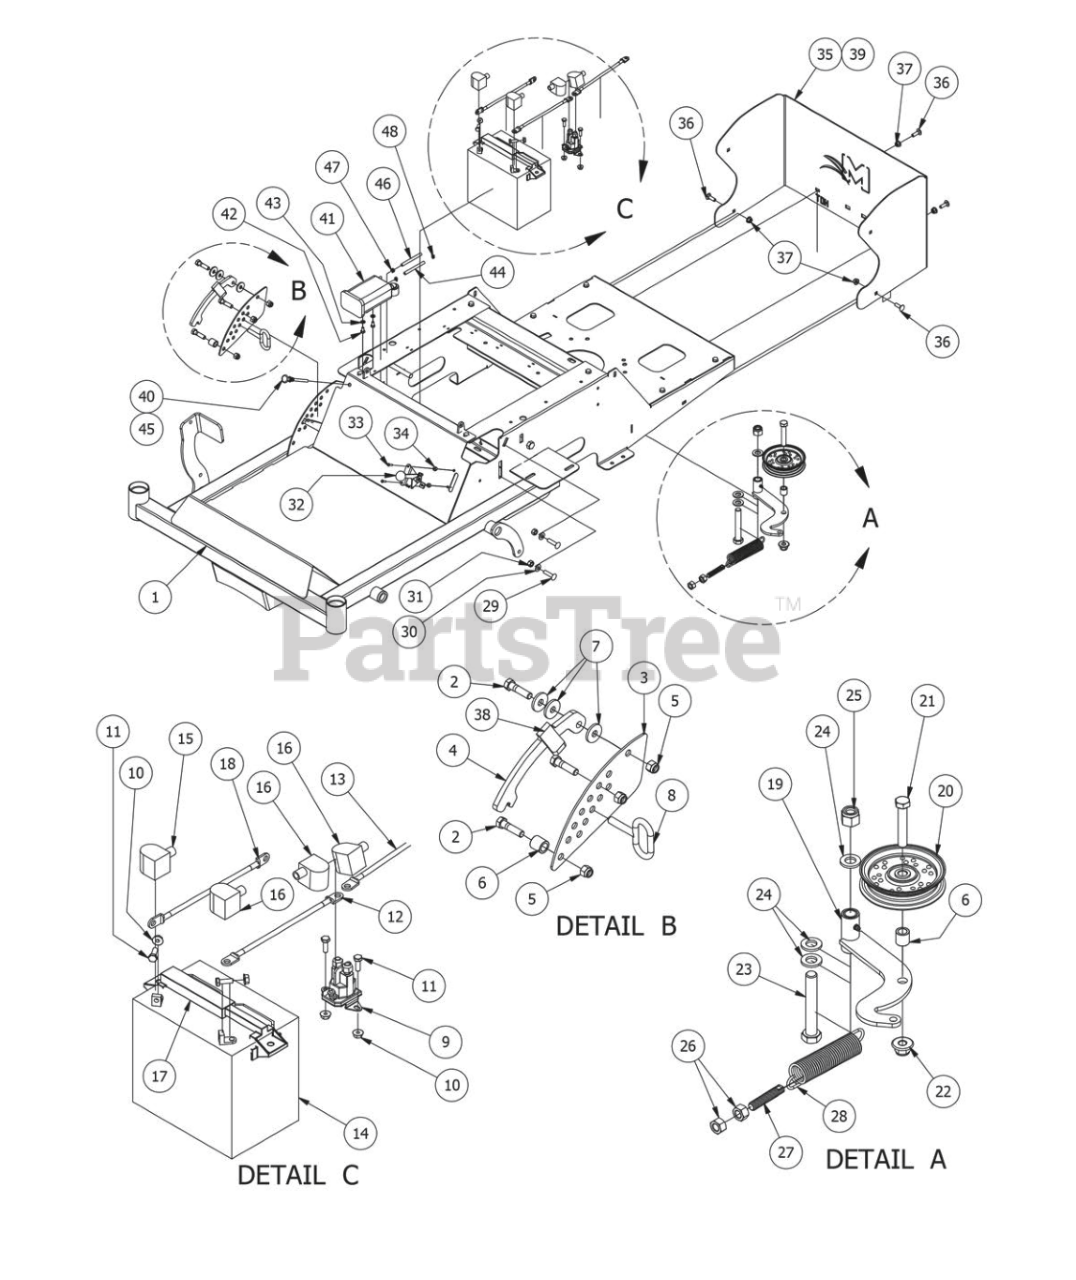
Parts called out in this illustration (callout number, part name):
2	3/8" x 1 1/2" Hex Bolt
3	MZ Height Indicator Plate
4	MZ Deck Level Lock Lever
5	3/8 Nylock Nut
6	3/4 OD x 1/2 ID x 3\4 Length
7	.390 ID Plastic Washer
8	Deck height lever pin
10	1/4-20 Hex Flange Nuts Zinc w/Serrations
11	1/4-20 x 3/4 GR 5 Hex Bolts Zinc
12	10" red battery cable
13	62" red cable
15	Black Boot For ground cable
17	Battery Hold Down
18	24" Ground Cable
19	MZ Idler arm Bracket
20	4 3/4 Idler Pulley-ABFI-76
21	1/2" x 2 3/4" Hex Bolt
22	1/2-13 Nylon Flange Nut-Orange
23	5/8" x 4" Hex Bolt
24	.635 ID Plastic Washer
25	5/8 Std NC Nylock Nut
26	1/2" Hex Nut
27	All Thread-pump Idler Tensioner
28	Deck spring big diameter
29	3/8-16 x 1-1/2 short neck bolt
30	3/8" Flat Washer
31	3/8" Hex Nut
32	Brake cable for MZ
33	10-24 X 5/8 BS C/S 18-8 SS
34	10-24 Nylon Insert Locknut
35	MZ Back Plate
36	5/16" x 1" Carriage Bolt
37	5/16" Flange Nut Zinc W/Serrations
38	Deck Height Handle Grip MZ
39	MZ Engine Rear Plate (21hp)
41	Carbon Canister for Magnum/MZ
42	M6-1.0 X 12MM Bolt 8.8
43	1/4" Lock Washer
44	3/16 vinyl tubing
45	Choke Kohler engine
46	1/4" vinyl tubing
47	1/4" vinyl clamp
48	3/16" Vinyl Hose Clamp
